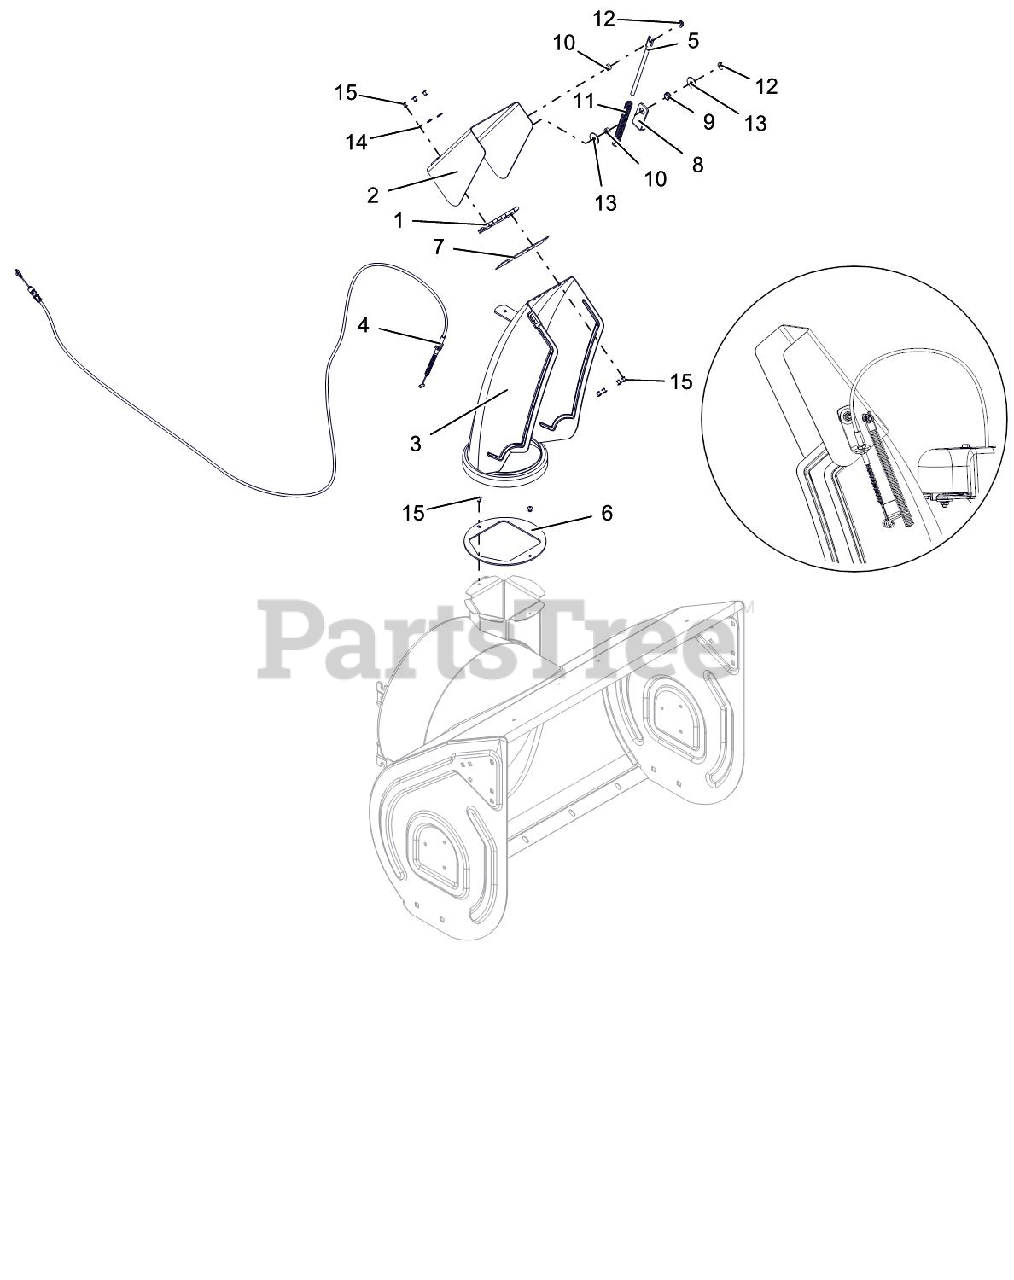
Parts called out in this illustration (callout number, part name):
2	CAP, LARGE REMOTE (W/DECAL)
3	CHUTE,DISCHARGE,NOTCHED,QT
4	CABLE, DEFLECTOR - DELUXE
5	ROD, DEFLECTOR CAP
6	BAFFLE, DISCHARGE NECK
7	CAP SEAL 5.50
8	BRACKET, CABLE ANCHOR
9	BUSHING, POLYLINER-.50 SNAPIN
10	BSHG-SLV .265X.500X.219
11	SG-COMP .08X.40X6.50 14#/IN
12	@NUT-LK-CTR-FLG .25-20 YWZC
13	WSHR-FL-STL .281X1.000X.063
14	WSHR-FL-STL .196X.500X.06 YZ
15	RVT-POP .187 YZ
